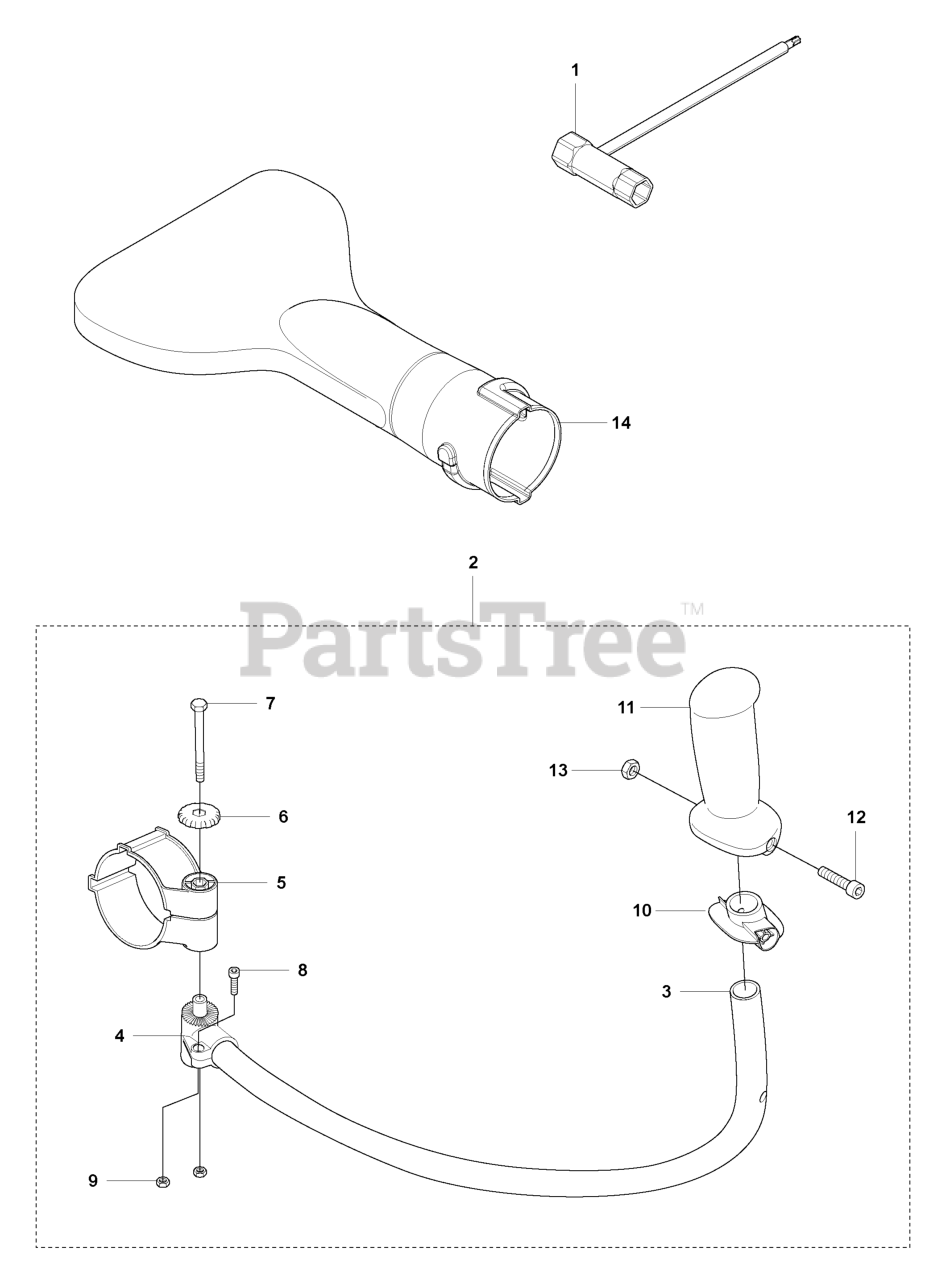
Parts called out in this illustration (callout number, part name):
1	SOCKET
2	HANDLEBAR ASSY
5	HOLDER TH
8	SCREW MC6S 5X10
14	FLAT NOZZLE
